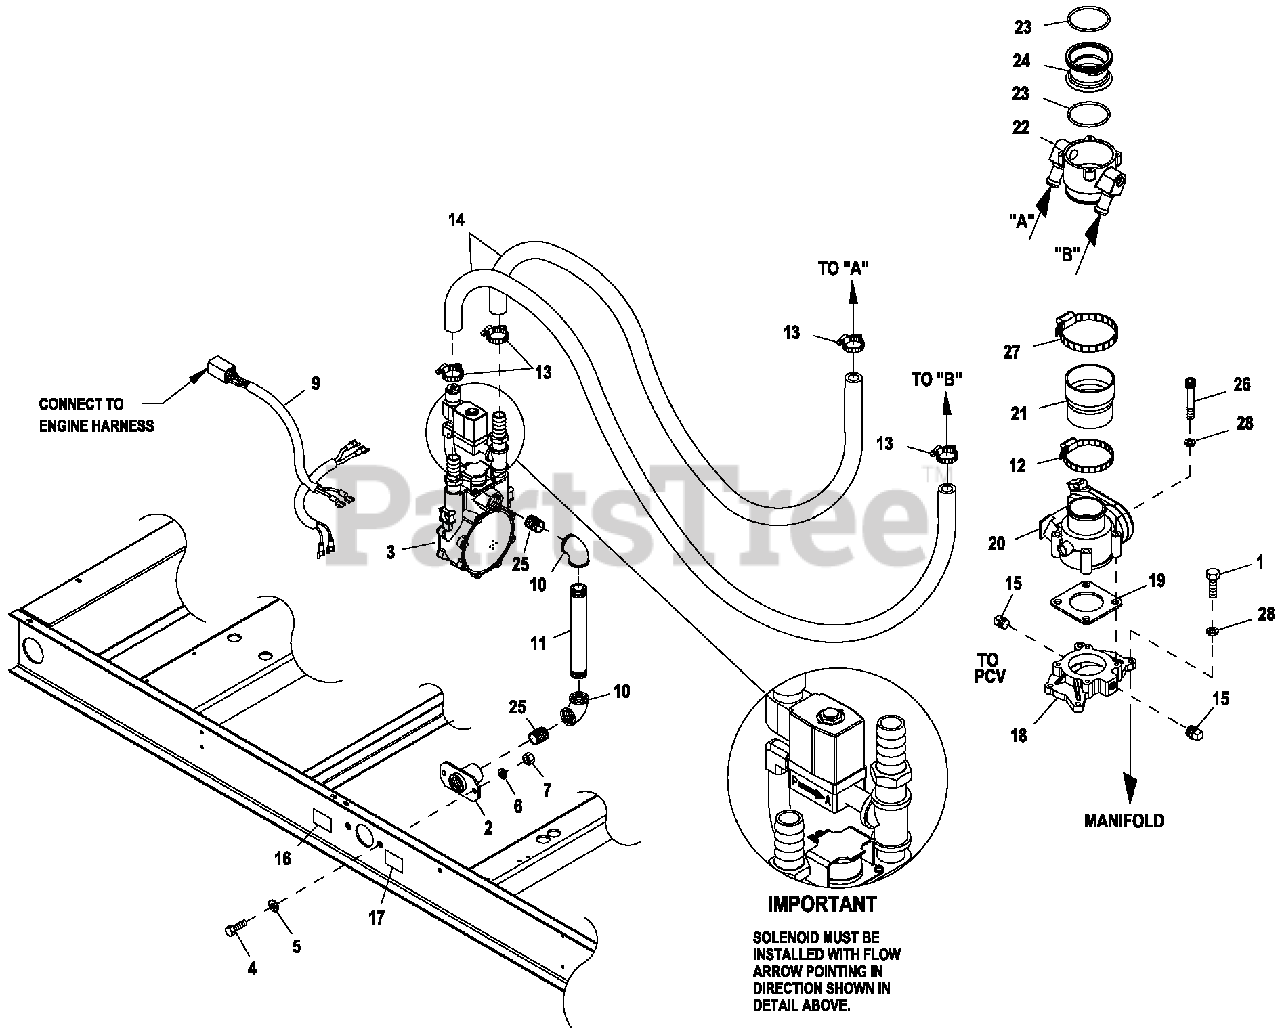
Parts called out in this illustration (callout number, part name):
1	SCREW HHC M6-1.0 X 25 G8.8
2	FLANGE FUEL INLET
3	REG A S SY 5.4L 55 KW NG CPL
4	SCREW HHC M8-1.25 X 20 G8.8
5	WASHER FLAT 5/16-M8 ZINC
6	WASHER LOC KM8-5/16
7	NUT HEX M8-1.25 G8 CLEAR ZINC
9	HARN FUEL JUMPER SINGLE REG
10	ELBOW 90D 3/4 NPT
11	NIPPLE PIPE 3/4 NPT X 7"
12	CLAMP HOSE #36 1.88-2.75
13	CLAMP HOSE #10 .56-1.06
14	HOSE 3/4 ID LPG & NG (40" LG)
15	PLUG STD PIPE 1/4 STEEL SQ HD
16	DECAL INLET PRESSURE
17	DECAL FUEL INLET NG (NATURAL GAS APPLICATION)
18	MACHINING INTA KE ADAPTOR 40MM
19	GAS KET BOSCH 32 & 40
20	ACTUATOR BOSCH 40 GOVERNOR
21	REDUCER RUBBER 3.0"-2.00"
22	MIXER, 40/60MM ACTUATOR A SSY
23	O-RING 2-3/4X3/32X2-15/16
24	VENTURI THROTTLE 32MM
25	NIPPLE CLOSE 3/4X1.375
26	SCREW SHC M6-1.0 X 50 C8.8
27	CLAMP HOSE #44 2.31-3.25
28	WASHER LOCK M6-1/4
